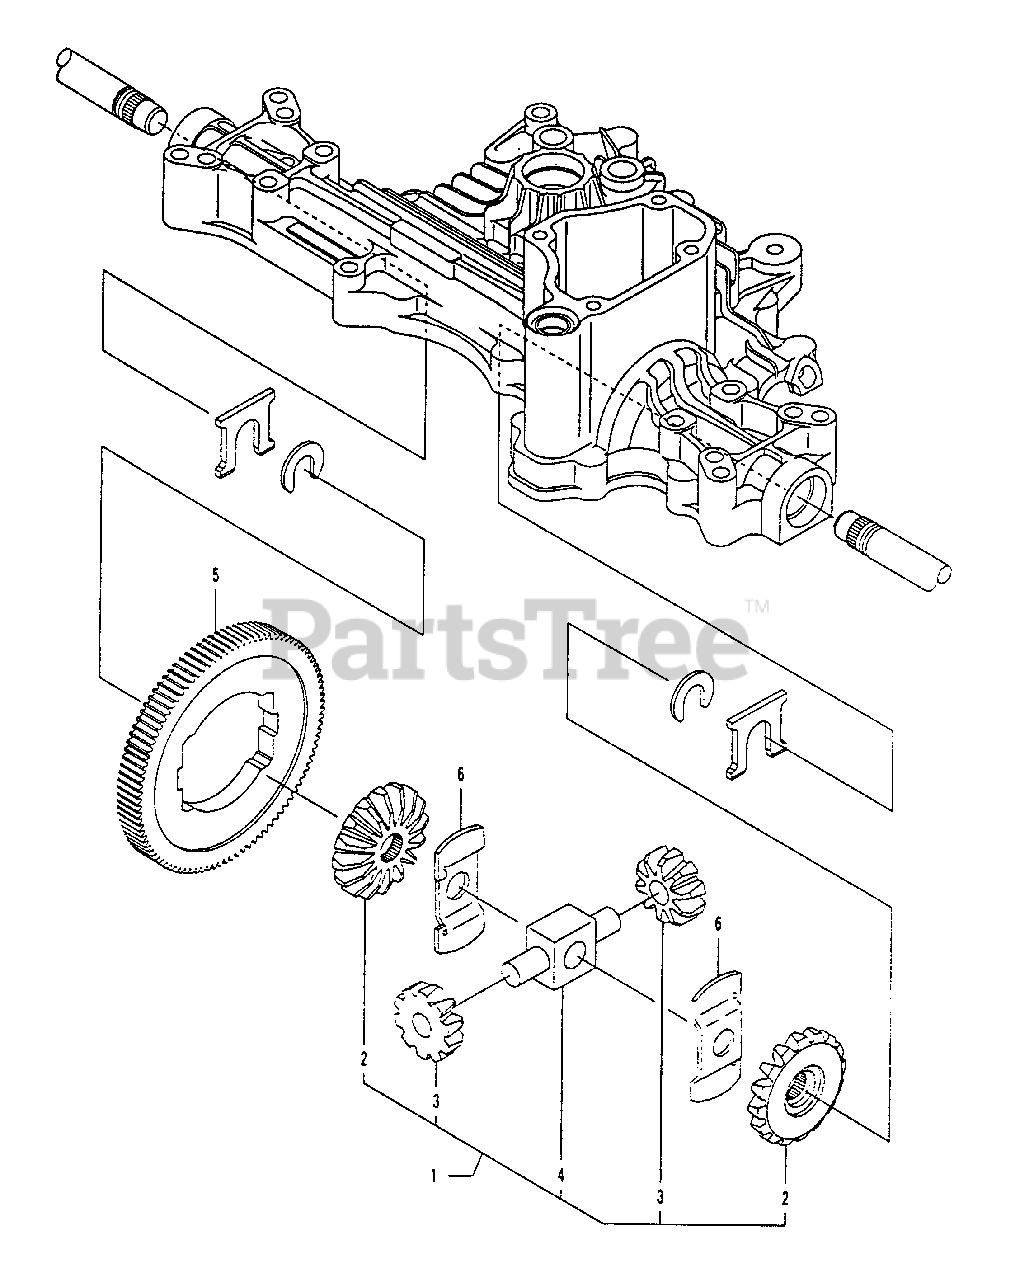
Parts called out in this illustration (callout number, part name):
1	DIFF. GEAR KIT
2	DIFF. SIDE GEAR
3	DIFF. PINION
4	SHAFT (DIFF. PINION
6	THRUST WASHER (DIFF.
